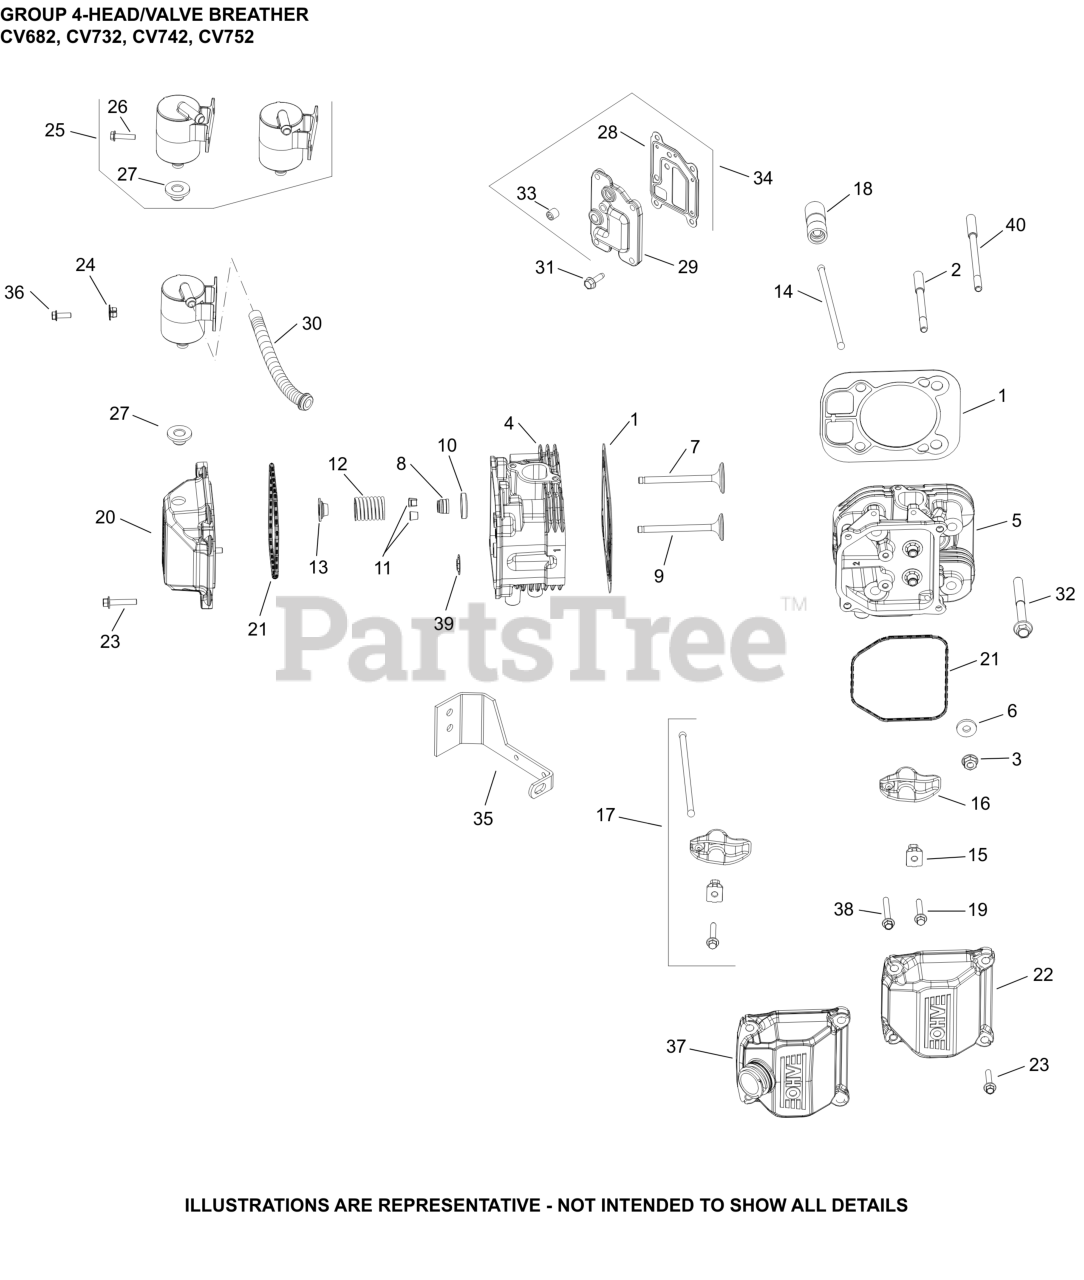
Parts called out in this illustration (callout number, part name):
1	KIT, GASKET CYLINDER HEAD
2	STUD, M8X1.25
3	NUT, FLG M8X1.25
4	KIT, CYLINDER HEAD (#1)-(#2481803S)
5	KIT, CYLINDER HEAD (#2)-(#2481804S)
6	WASHER, FLAT 8.6 MM
7	VALVE, INTAKE (STD)
7	VALVE, INTAKE (.25)-(#DSC)
8	SEAL, VALVE BAND
9	VALVE, EXHAUST
9	VALVE, EXHAUST (.25)
10	RETAINER, SPRING
11	KIT, RETAINER
12	SPRING, VALVE
13	CAP, VALVE SPRING
14	ROD, PUSH
15	PIVOT, ROCKER ARM
16	ARM, ROCKER
17	KIT, VALVE TRAIN
18	LIFTER, VALVE HYDRAULIC-USE 25 351 11-S
20	KIT, VALVE COVER
21	O-RING (YELLOW), VALVE CO
22	KIT, VALVE COVER-PLAIN (PLASTIC)
24	NUT, PLASTIC
25	KIT, BREATHER SEPARATOR
27	GROMMET, RUBBER
28	GASKET, BREATHER
30	HOSE, BREATHER VERTICAL HDAC
31	SCREW, THREAD FORMING
34	KIT, BREATHER COVER W/GASKET
36	SCREW, HI-LOW
38	SCREW, HEX FLANGE
39	RETAINER, VALVE GUIDE (KM)
NI	SCREW, HEX FLANGE (M6 X 31.625 DOG PT)
